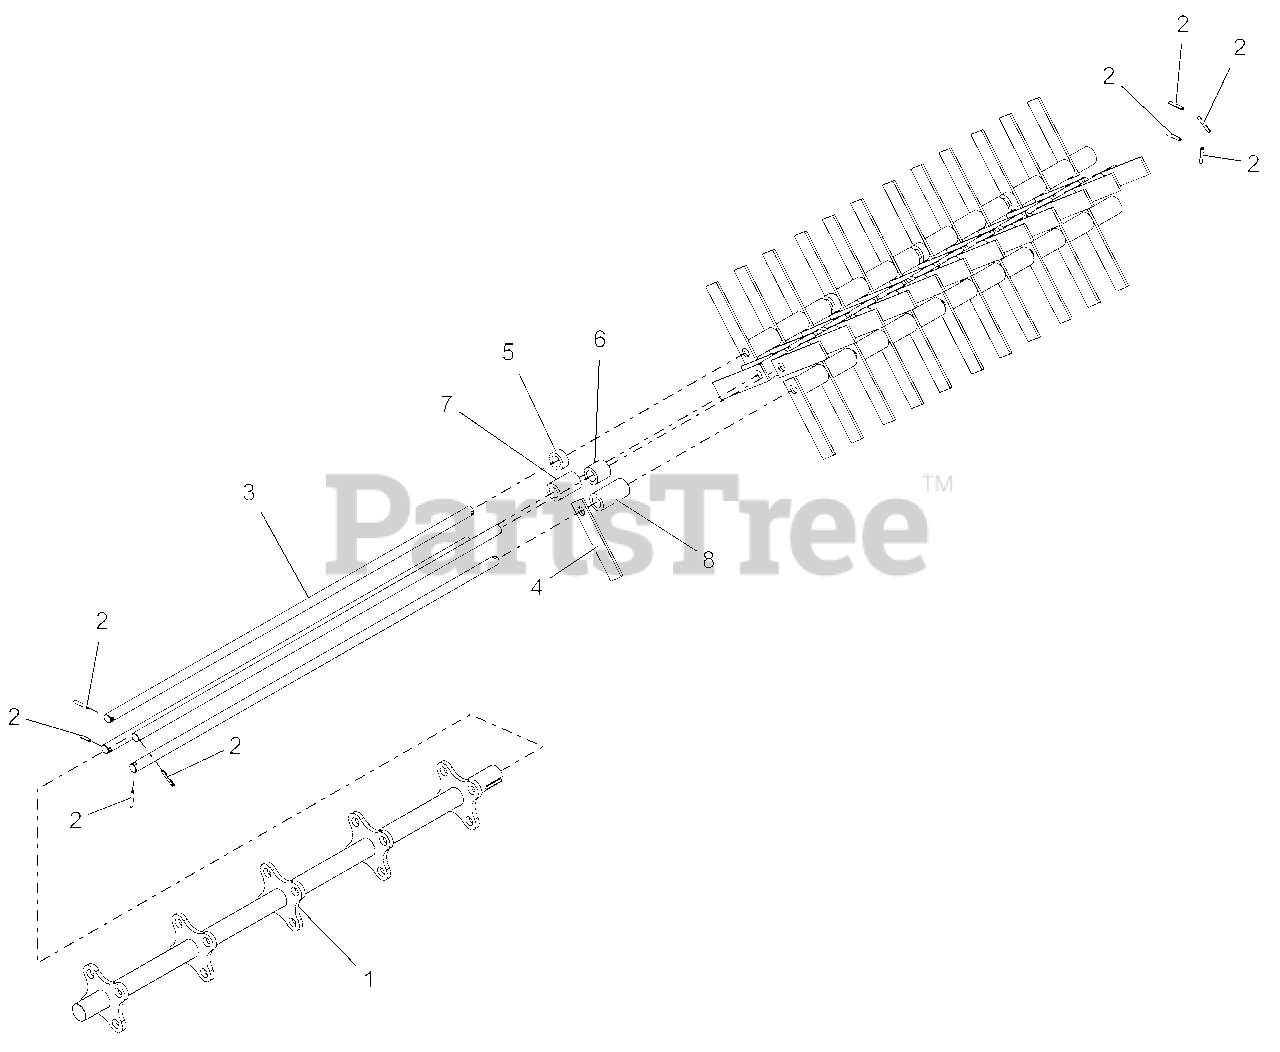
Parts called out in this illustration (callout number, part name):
1	WLDMT, FLAIL TINE MNT
2	PIN, SPRING 5/32 X 1
3	ROD, FLAIL MNT
4	BLADE, THATCHING
5	SPACER, SHORT END-FLAIL
6	SPACER, SHORT-FLAIL
7	SPACER, MED. FLAIL
8	SPACER, LONG FLAIL
